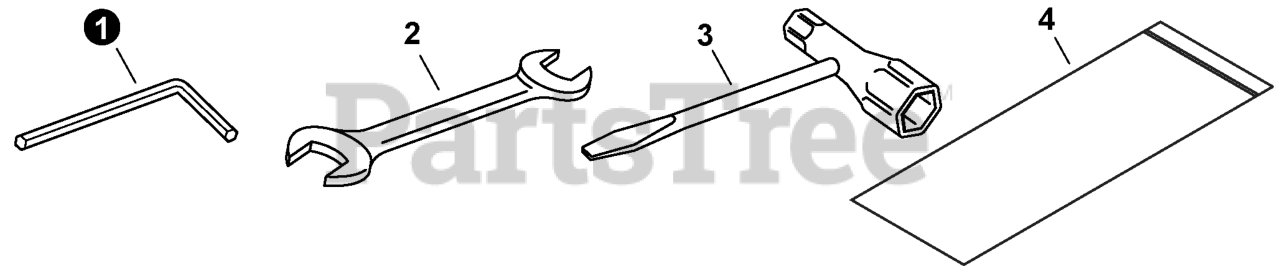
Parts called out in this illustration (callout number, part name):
1	WRENCH, ALLEN 4 MM
2	SPANNER 8x10
3	T-WRENCH 13x19x180
4	BAG, TOOL
